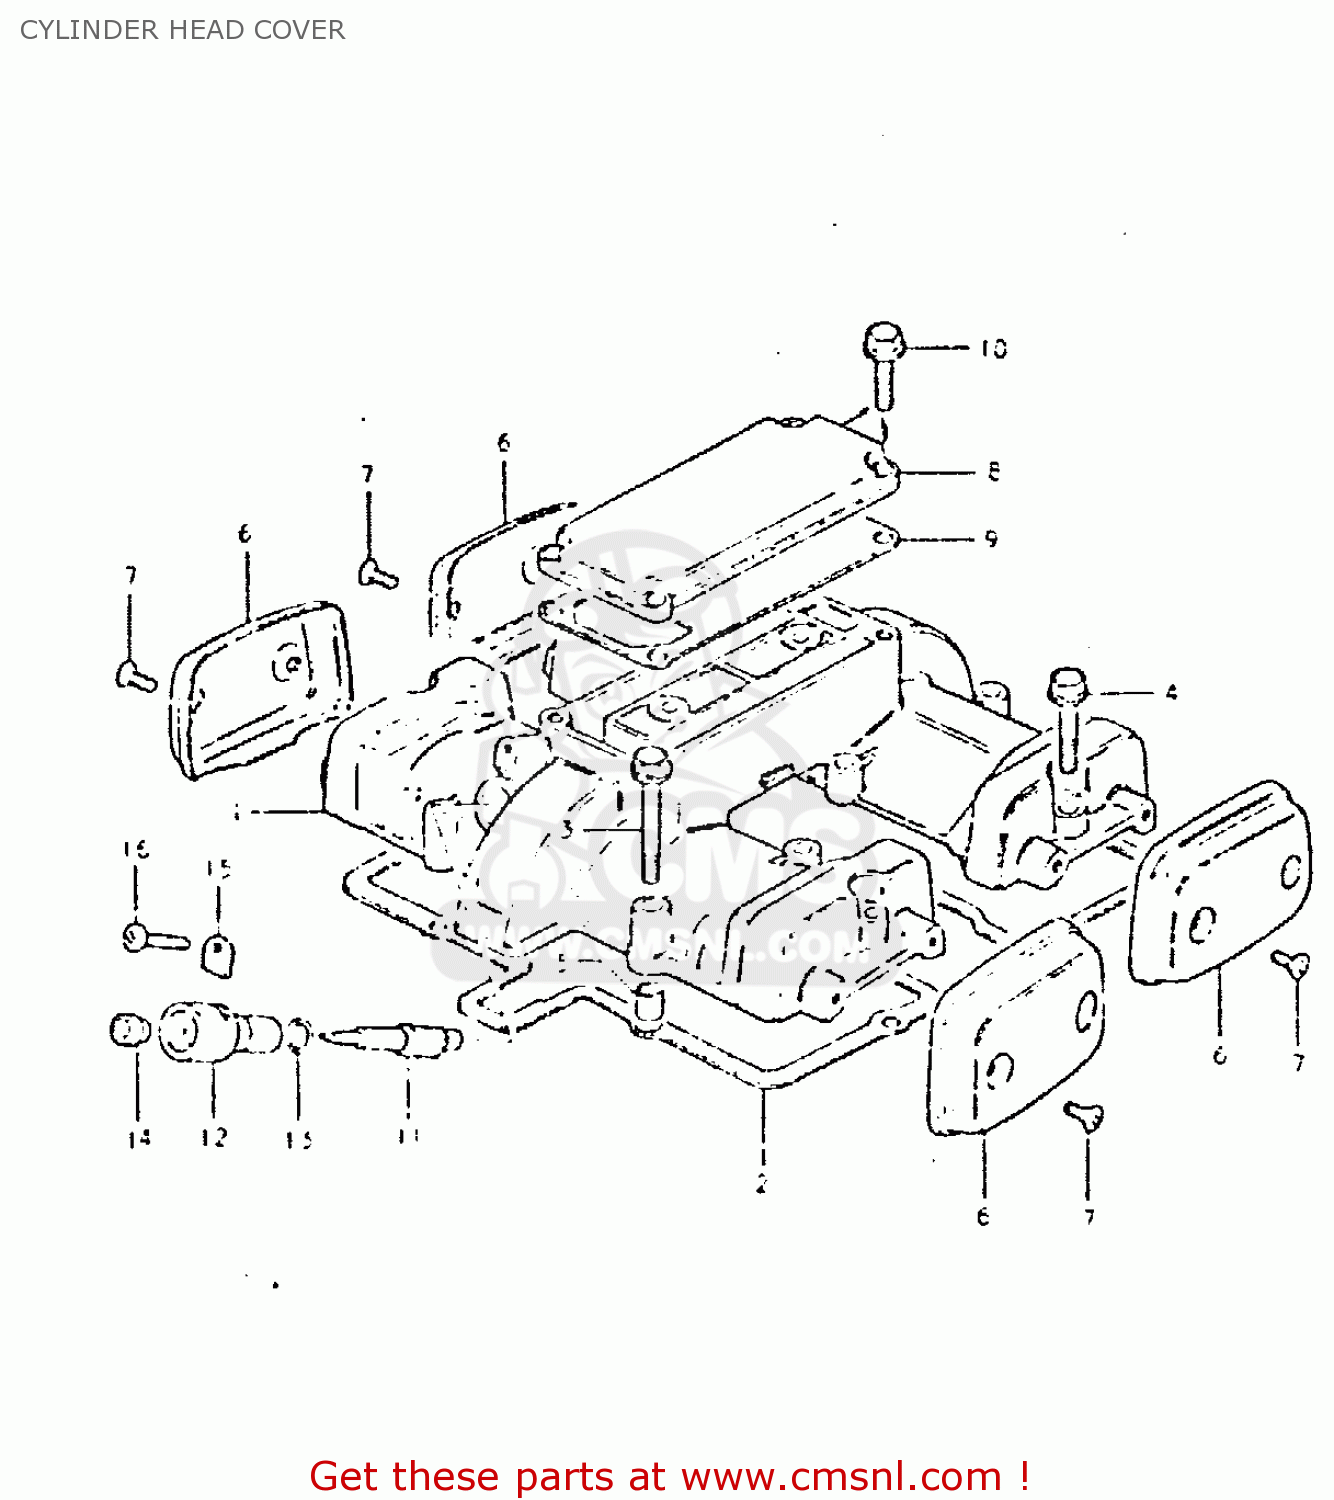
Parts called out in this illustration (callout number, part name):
1	COVER, CYLINDER HEAD
2	GASKET (MCA)
3	BOLT 6X35
4	BOLT
5	PIN(6.2X8X11)
6	UNION,CYLINDER HEAD OIL
7	SCREW 5X12
8	COVER,BREATHER
9	GASKET (MCA)
10	BOLT,REAR
11	GEAR,TACHOMETER DRIVEN
12	SLEEVE,TACHOMETER DRIVE
13	SEAL,TACHOMETER DRIVEN
14	SEAL,OIL(5X12X8)
15	PLATE,TACH DRIVE GEAR SLEEVE
16	SCREW(5X12)
